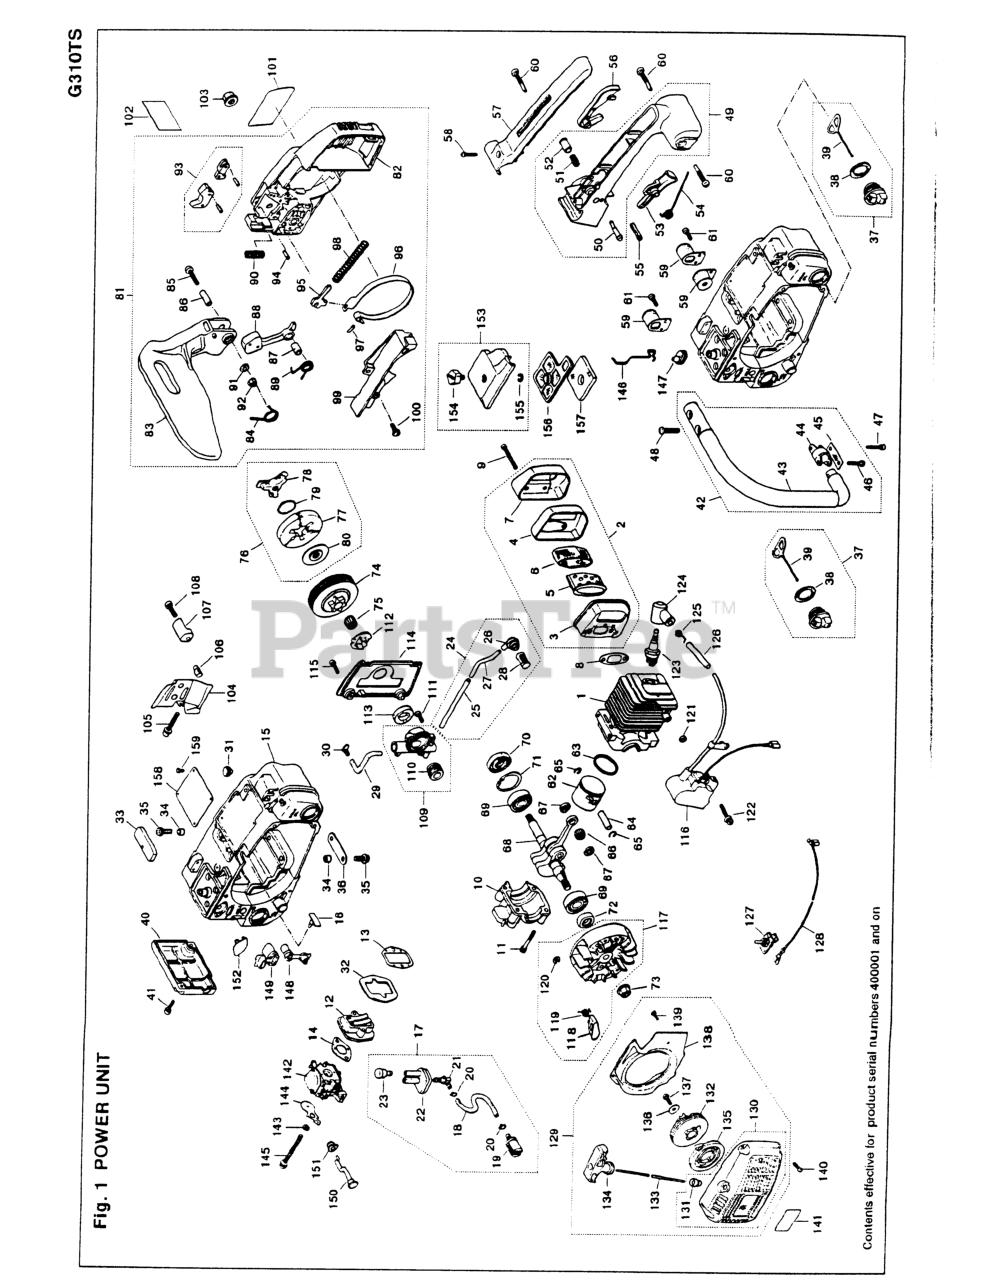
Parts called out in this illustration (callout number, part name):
1	CYLINDER
2	MUFFLER ASSEMBLY
4	COVER
5	BAFFLE
6	ARRESTER
8	GASKET
10	CRANKCASE
11	BOLT, M5 X 30
12	VALVE ASSEMBLY
13	GASKET (USE -22211)
14	GASKET, CARB (USE -14121)
17	PIPE COMP (USE -31202)
18	PIPE (USE -85411)
19	5500-85400 (RRLS. 1750-85300)
20	CLIP (REPLACES 2841-31280)
22	GROMMET
23	BREATHER ASSY (RPLS 2630-31270
24	PIPE ASSEMBLY
25	PIPE (USE -85411)
26	GROMMET (RPLS -31320)
29	PIPE (USE -85411)
30	PIN
31	VALVE A
32	SEAL
35	SCREW
38	GASKET
39	STOPPER (RPLS 3317-57240)
40	COVER (RPLS -31912)
41	SCREW
42	HANDLE, FRONT (RPLS -32102)
44	JOINT (RPLS -32120)
45	STOPPER (RPLS -32150)
49	HANDLE, REAR (RPLS -33101)
50	STOPPER
52	KNOB
54	SPRING
58	SCREW
59	JOINT (RPLS -33510)
61	SCREW (REPLACES 50030272)
62	PISTON
63	RING
64	PIN, PISTON
65	RING, SNAP
66	BEARING
67	WASHER (RPLS 3310-41341)
68	CRANKSHAFT
70	SEAL, OIL
71	RING, SNAP, M32 x 1.2
74	DRUM (RPLS 2631-51111)
75	BEARING
79	SPRING
80	BOSS (A)
85	SCREW
91	WASHER, M5 X .8
92	NUT (B)
93	LEVER, BRAKE COMPLETE
95	ARM, SLIDE
96	BAND
97	PIN
98	SPRING, BRAKE (RPLS. 50030121)
100	SCREW (REPLACES 50030272)
103	NUT
106	NUT
107	CATCHER, CHAIN (RPLS. -53411)
110	GEAR
112	PLATE
113	SEAL
114	COVER, PUMP (RPLS -55311)
115	SCREW
117	ROTOR (RPLS -71200)
118	PAWL (RPLS -71220)
119	SPRING (RPLS -71230)
120	RING, SNAP, M4
122	BOLT
125	SPRING
127	SWITCH A
129	STARTER ASSEMBLY
131	GUIDE (RPLS -75120)
132	REEL (RPLS -75211 & -75210)
134	KNOB (RPLS -75420)
135	HOLDER COMPLETE
139	SCREW (REPLACES 50030272)
140	SCREW
142	CARBURETOR
147	GROMMET
148	GROMMET A
151	GROMMET
152	CAP
155	RING, SNAP, M4
158	LABEL (USE -31411)
